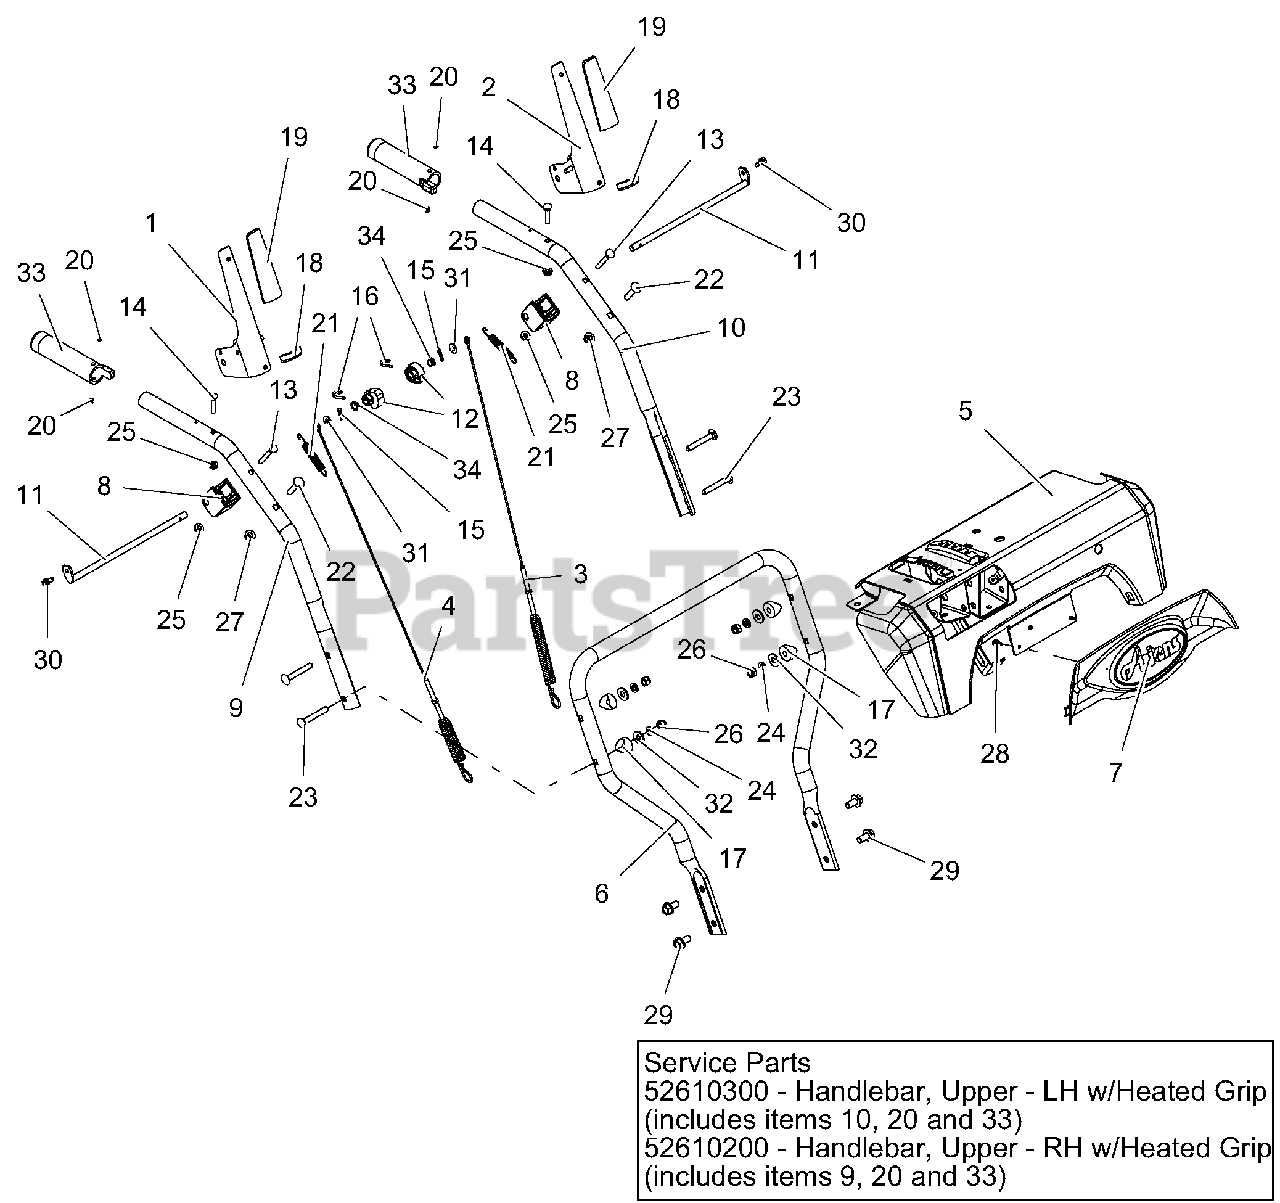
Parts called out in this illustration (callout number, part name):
1	LEVER, CLUTCH-RH
2	LEVER, CLUTCH-LH
3	CABLE, UPPER TRACTION
4	CABLE, AUGER (DELUXE & PRO)
5	CONTROL PANEL W/DECAL HW,ID,AD
6	HANDLEBAR, LOWER - DELUXE
7	DASH BEZEL, ARIENS LOGO - PRO
8	BLOCK, CLUTCH PADDLE
9	HANDLEBAR, UPPER - RH
10	HANDLEBAR, UPPER - LH
11	ROD, PADDLE MOUNT - PRO
12	CAM, INTERLOCK
13	BLT-RDHDXLSQNK .25-20X2.0 G5YZ
14	BLT-RDHDXLSQNK.25-20X1.25 G5ZC
15	PIN-HAIR INT .06X.18X.77
16	PIN, SPRING CLIP
17	SPACER, HANDLEBAR
18	EDGING, CLUTCH PADDLE - 2.00"
19	CLUTCH PADDLE SLEEVE - GRAY
20	RVT-POP #43 .125X.313 STL ZINC
21	SPRING, EXTENSION
22	@BLT-RDHDSQNK .31-18X1.50 G5YZ
23	@BLT-RDHDSQNK .31-18X2.25 G5YZ
24	WSHR-LK .312X.097 HVY YWZC
25	@NUT-LK-CTR-FLG .25-20 YWZC
26	@NUT-LK-NYL .312-18 YWZC
27	@NUT-LK-TOP-FLG .31-18 YWZC
28	SCR-TAP #10X.50 BOSS INDHXHD
29	BLT-SERHFWH .38-16X.75 YWZC
30	SCR-TAP .25-20X.50 HWH TR YWZ
31	@WSHR-FL-STL.281X.62X.065 YWZC
32	@WSHR-FL-STL.38X.875X.083 YWZC
33	HEATED GRIP, MAGURA
34	BUSHING, POLYLINER-.38 SNAPIN
